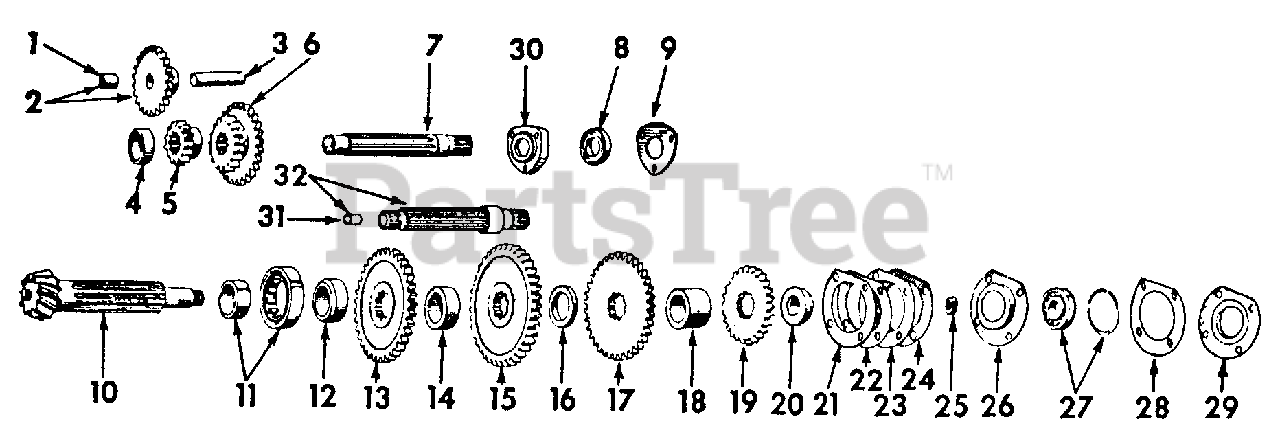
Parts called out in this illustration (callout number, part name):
1	Bushing, Reverse Idler Gear
2	Gear w/Bushing, Reverse Idler -22T
3	Shaft, Reverse Idler
4	Bearing Assy, Transmission Main Shaft Rear Needle
5	Gear, First & Reverse Speed Sliding -13T
6	Gear, Second & Third Speed Sliding -17T & 26T
7	Shaft, Transmission Main
8	Bearing Assy, Transmission Main Shaft Front Ball
9	Retainer, Transmission Main Shaft Front Brg
10	Countershaft & Bevel Pinion -10T
11	Bearing Assy, Countershaft Rear Roller
12	Spacer, Reverse Speed Gear & Countershaft Brg
13	Gear, Reverse Speed -35T
14	Spacer, First & Reverse Speed Gear
15	Gear, First Speed -39T
16	Spacer, First & Second Speed Gear
17	Gear, Second Speed -35T
18	Spacer, Second & Third Speed Gear
19	Gear, Third Speed -26T
20	Spacer, Third Speed Gear & Countershaft Brg
21	Shim, Countershaft Brg Retainer, .004
22	Shim, Countershaft Brg Retainer, .007
23	Shim, Countershaft Brg Retainer, .0149
24	Shim, Countershaft Brg Retainer, .0299
25	Nut, Countershaft Front Brg Lock
26	Not used in this application
27	Bearing Assy, Countershaft Front Ball
28	Gasket, Countershaft Brg Retainer
29	Retainer, Countershaft Brg
30	Cage, Transmission Main Shaft Front Brg
31	Bushing, PTO Shaft Pilot
32	Shaft Assy, Transmission Input
